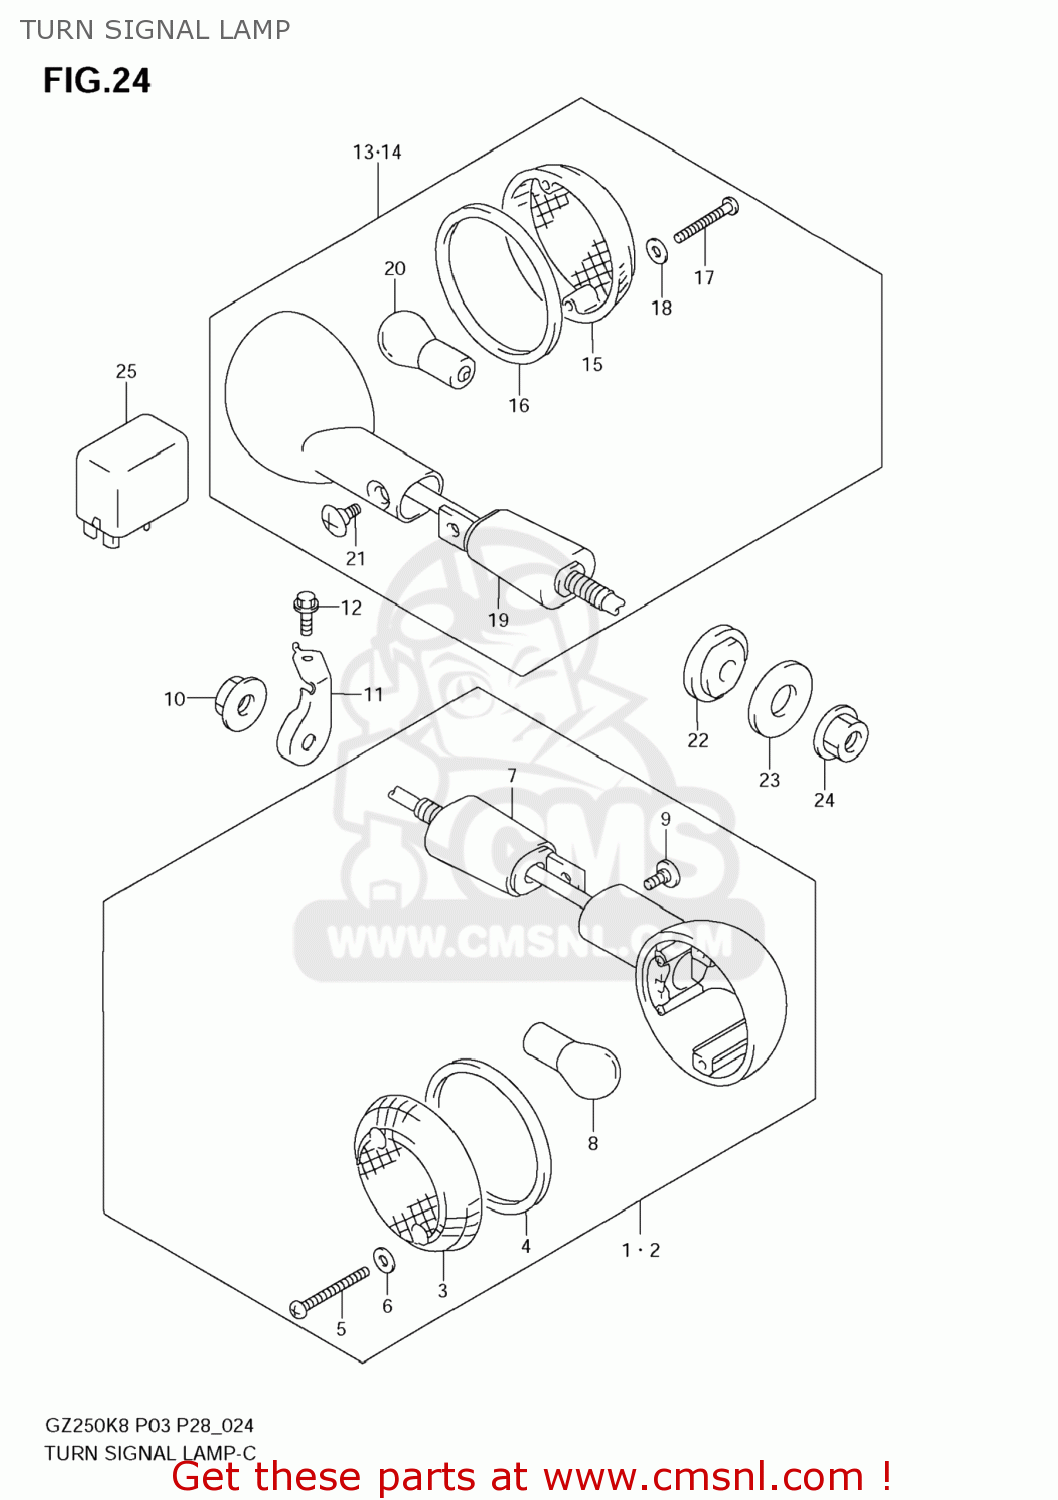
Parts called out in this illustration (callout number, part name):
1	LAMP ASSY,FR TURN SIGNAL,R
2	LAMP ASSY,FR TURN SIGNAL,L
3	LENS
4	GASKET (NAS)
5	SCREW
6	GASKET (NAS)
7	STAY,TURNSIGNAL FR
8	BULB(12V21/5W)
9	SCREW
10	NUT
11	BRACKET,FR TURNSIGNAL,R
12	BOLT
13	LAMP ASSY,RR TURNSIGNAL,R
14	LAMP ASSY,RR TURNSIGNAL,L
15	LENS
16	GASKET (NAS)
17	SCREW
18	GASKET (NAS)
19	STAY,TURNSIGNAL RR
20	BULB(12V21W)
21	SCREW
22	SPACER,RR TURNSIGNAL
23	WASHER(10.5X30X2.3)
24	NUT
25	RELAY ASSY,TURNSIGNAL LAMP
